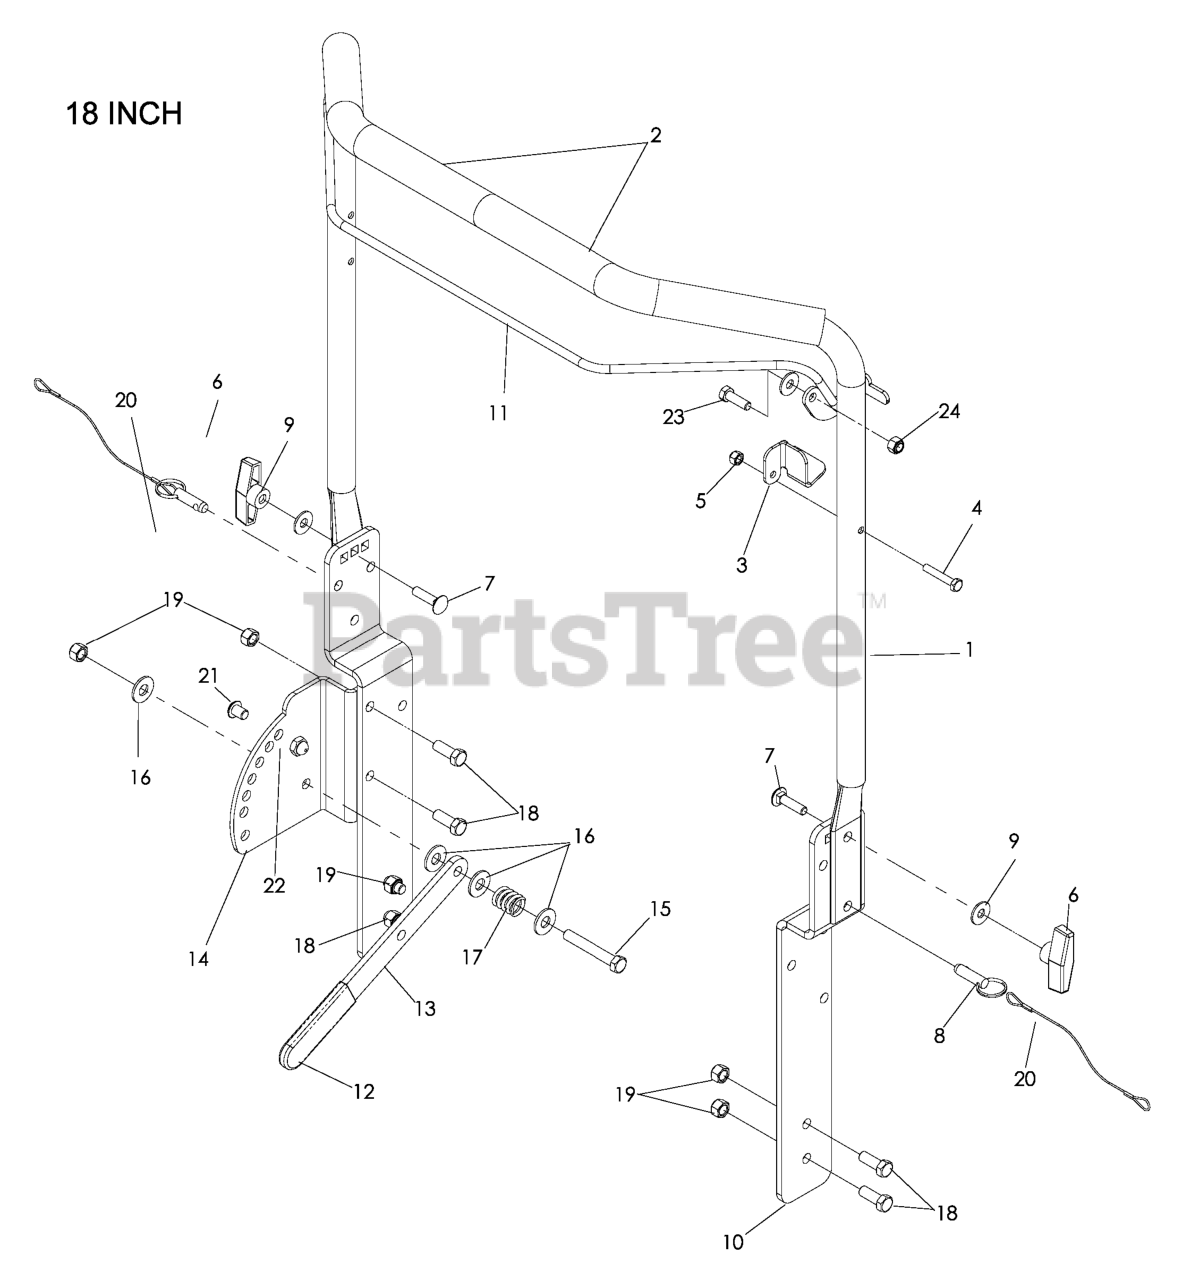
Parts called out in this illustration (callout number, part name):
1	HANDLE GRAY
3	CABLE TAB POWER RAKE
4	SCW 1/4-20 X 1-1/2 HEX
5	NUT.1/4-20.HEX.NYLOC.ZD
7	BOLT, CARRIAGE 5/16X1-1/4
8	DETENT PIN RAKE/DT
9	WASHER 5/16 FLAT
10	HANDLE SIDE GREY
11	BAIL - ORANGE
13	LEVER, PLATED
14	HEIGHT ADJUSTMENT PLATE
15	HCS 3/8C X 2 1/2
16	WASHER 3/8 FLAT
17	COMPRESSION SPRING
18	HCS 3/8-16X1.GRD.5.ZD
19	NUT 3/8-16 NYLOC
21	BLT 3/8-16 X 1/2 BTN HD BLK SP
22	NUT 3/8-16 ACORN HEX
23	HCS 5/16C X 1
24	NUT 5/16 NYLOC
